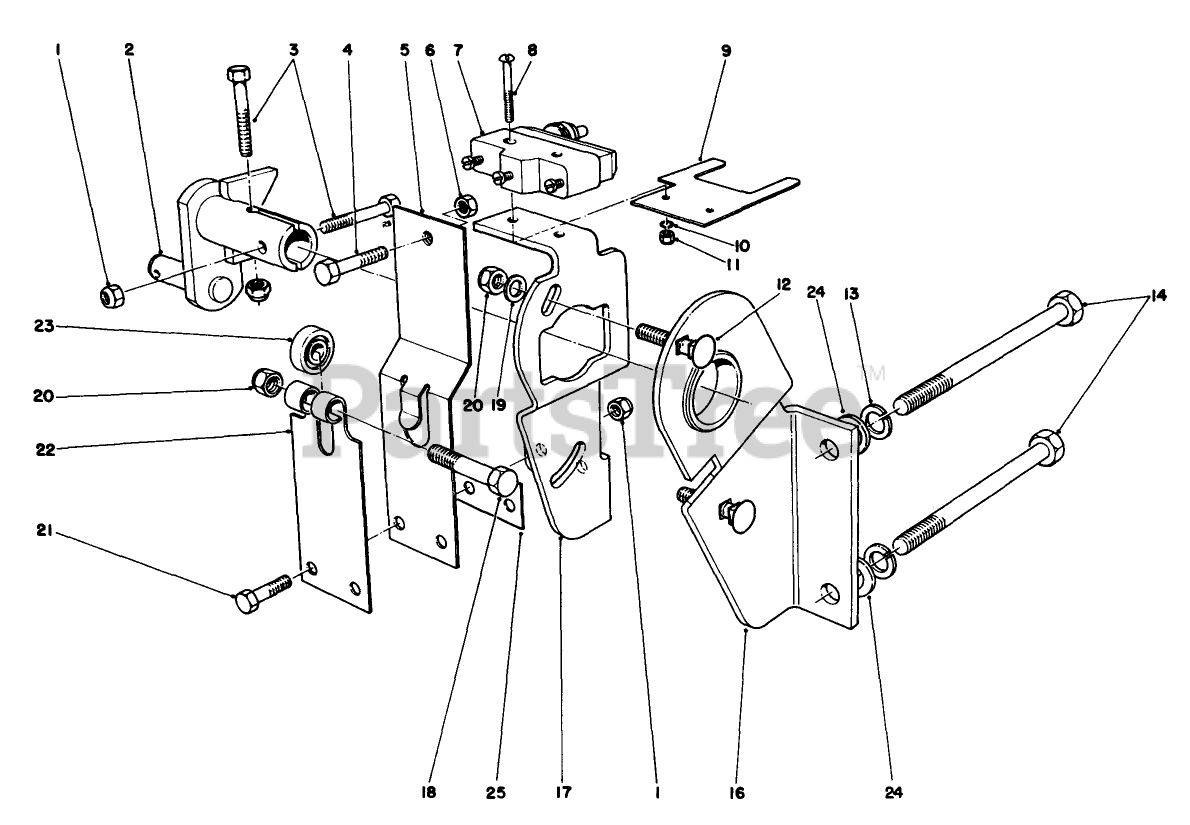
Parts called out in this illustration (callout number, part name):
1	NUT-LOCK, NI
2	Lever-Pump
3	SCREW-HH
4	SCREW-HH
5	EXTENDED LEAF SPRING ASM
6	NUT-HEX
7	Micro Switch
8	SCREW-MACHINE
9	STOP-SPRING, LEAF
10	WASHER-LOCK, INTERNAL
11	NUT-HEX
12	BOLT-CARR
13	WASHER-LOCK
14	SCREW-HH
16	Bracket-Mounting
17	PLATE-PUMP
18	SCREW-HH
19	WASHER-FLAT
20	NUT-LOCK, NI
21	SCREW-HH
22	SPRING-LEAF
23	BEARING-BALL
24	WASHER-FLAT
25	SHIM-ARM, SPRING
